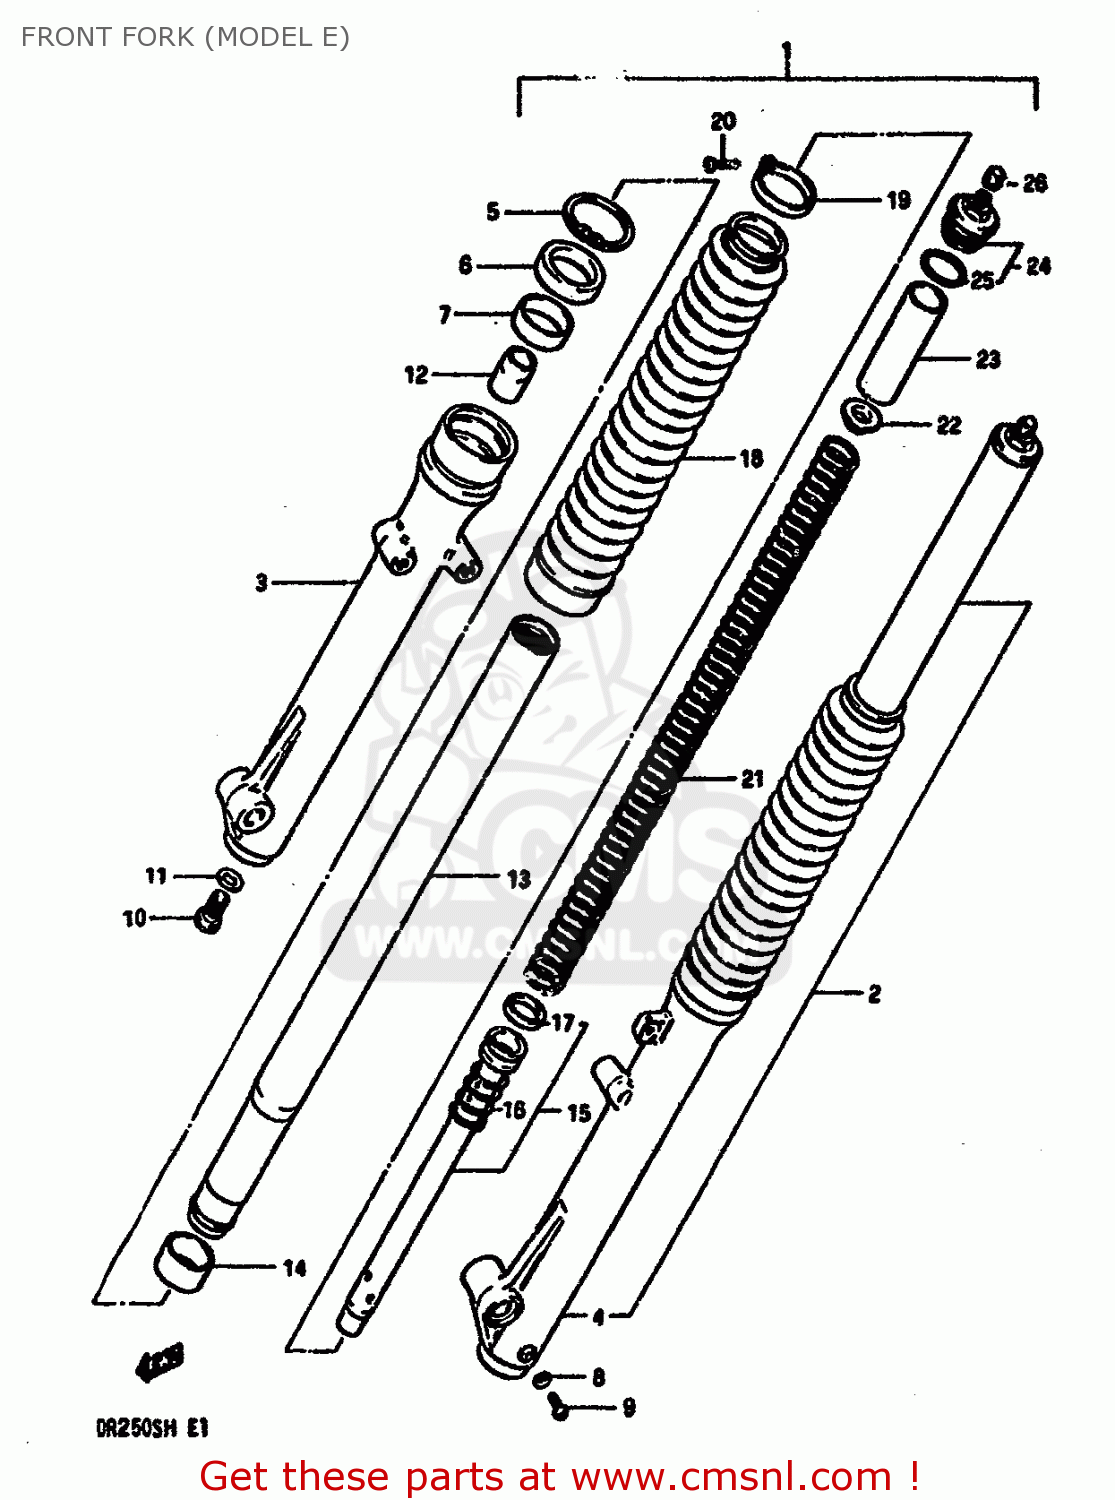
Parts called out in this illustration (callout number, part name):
1	DAMPER ASSY,RH (BLUE)
2	DAMPER ASSY,LH (BLUE)
3	TUBE,FORK,OUTER,RIGHT
4	TUBE,FORK,LEFT,OUTER
5	6
6	SEAL,OIL
7	SLIDE METAL
8	GASKET,DRAIN,PLUG (NAS)
9	SCREW
10	BOLT,FORK CYLINDER(10X25)
11	GASKET (NAS)
12	PIECE,OIL LOCK
13	INNER TUBE
14	PISTON
15	CYLINDER,FRONT FORK
16	SPRING
17	RING,FRONT FORK PISTON
18	BOOT (BLUE)
19	BAND,BOOT
20	SCREW
21	SPRING
22	GUIDE,FRONT FORK SPRING C
23	COLLAR,SPRING
24	CAP,FR FORK INNER TUBE
25	O RING
26	CAP
